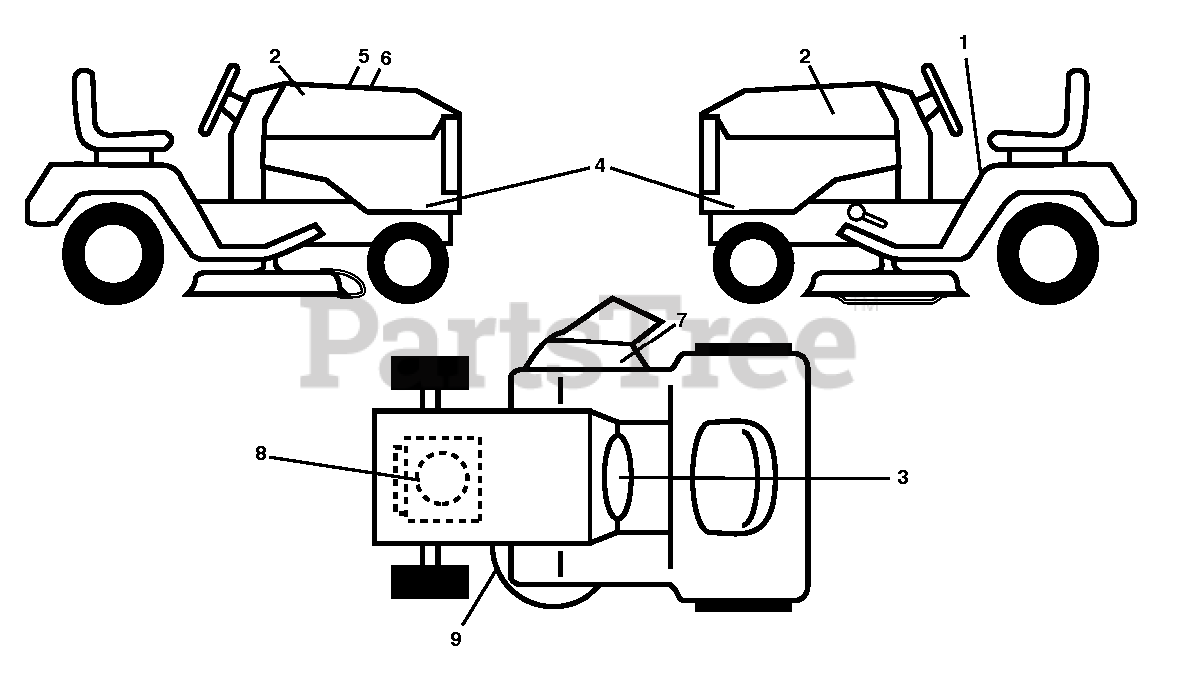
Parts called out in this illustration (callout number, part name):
1	DECAL.FENDER.WARNING.ENGLISH
2	DECAL.BADGE.170MM.TEXTLOGO.
3	DECALS.WARN.CA.SPKARREST/PROP
4	DECAL TRACTOR SIDE PANEL DECAL
5	DECAL.WARNING.CUST.RESP.E85.
6	DECAL.RPL.BSM33.INTK.TLW
7	DECAL, DECK DEFLECTOR, WARNING
8	DECAL.ENG.BS.18.5INTK.381713
9	DECAL.V-BELT.SCH.42/46"MEC/ELE
